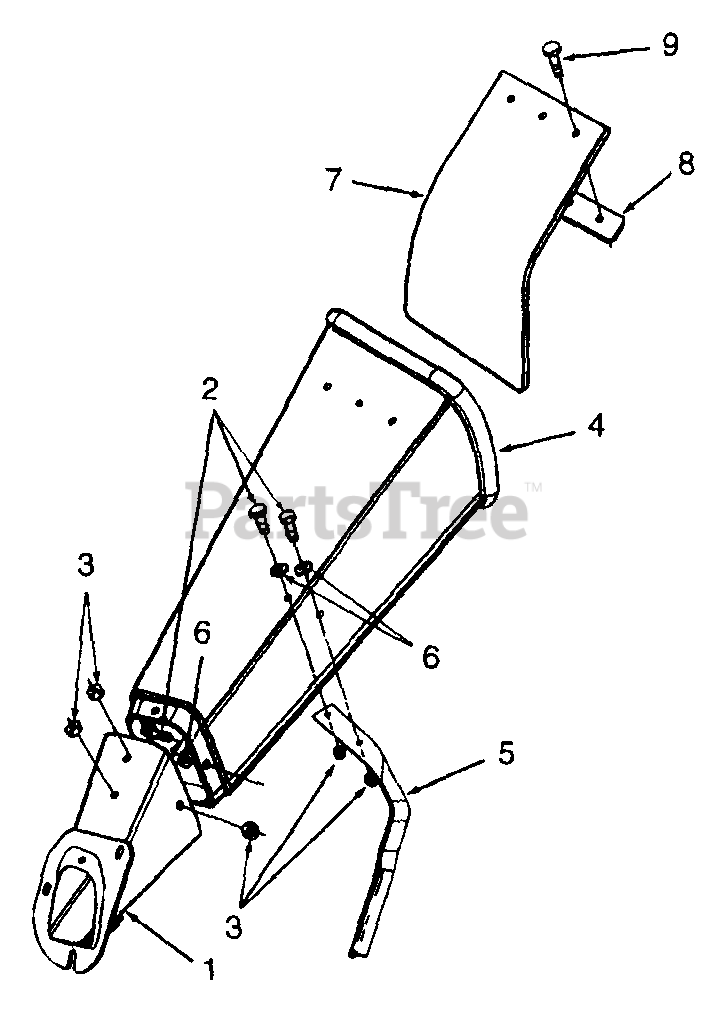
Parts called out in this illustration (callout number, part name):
1	Chute Assembly, Chipper
2	Screw, Hex Cap, 1/4-20 x .625
3	Nut, Hex Flange Lock, 1/4-20
4	Chute, Chipper
5	Bracket, Chipper Chute Support
6	Washer, Flat, .28 x .74 x .63
7	Flap, Chipper Chute
8	Strip, Chute Flap
9	Rivet, Pop, .156 x .504
